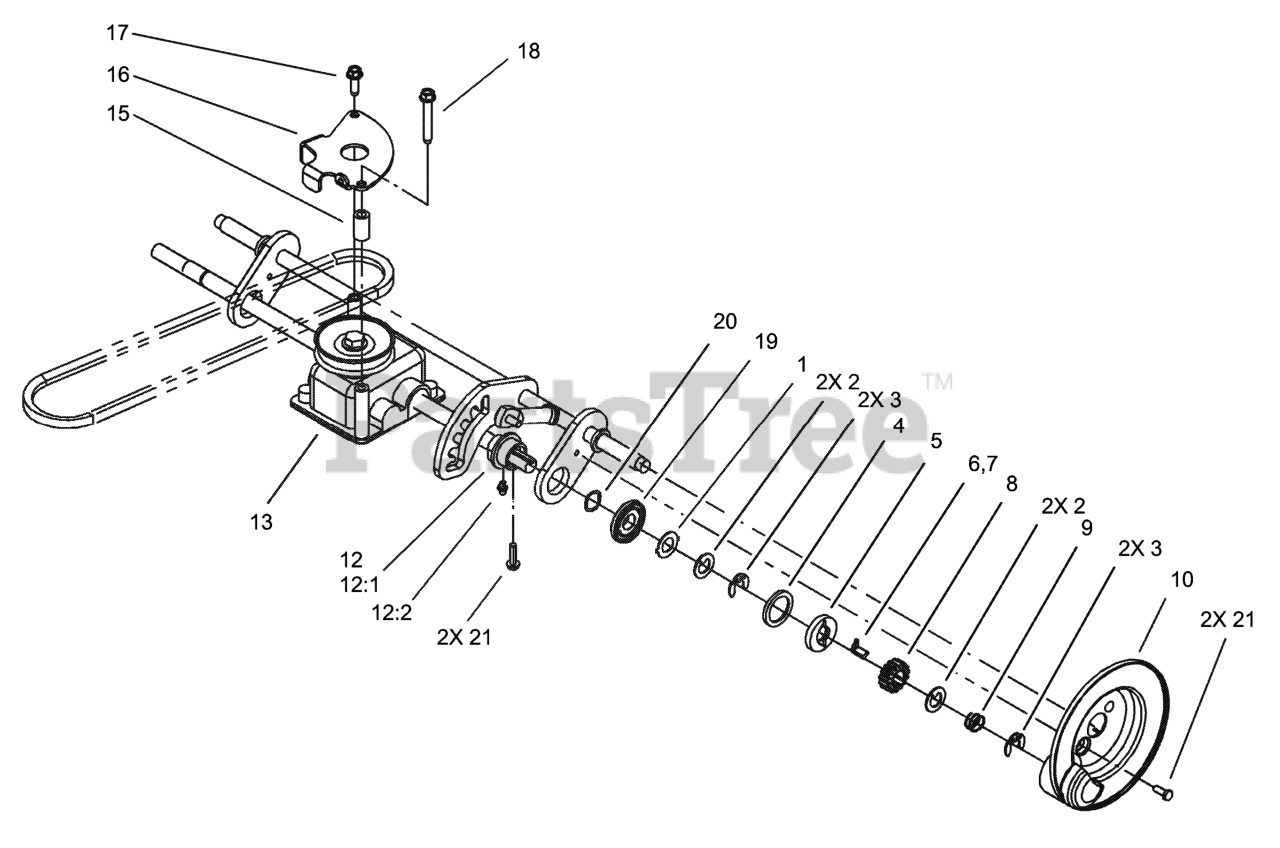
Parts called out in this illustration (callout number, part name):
1	WASHER-ARM, PIVOT
2	WASHER-THRUST, KEYED
3	RING-CLIP, LOCKING
4	RING-FRICTION
5	WASHER-CLUTCH
6	KEY-ROCKING, RH
7	KEY-ROCKING, LH
8	GEAR-PINION
9	SPRING-COMPRESSION
10	COVER-GEAR
12	BUSHING ASM
12:1	BUSHING
12:2	FITTING-GREASE
13	GEAR CASE ASM
15	BUSHING-PLATE, ACTUATOR
16	GUIDE-TRANSMISSION
17	SCREW-HWHTF
18	SCREW-HWHTF
19	RETAINER-RING
20	WASHER-WAVE
21	SCREW-TAPTITE
